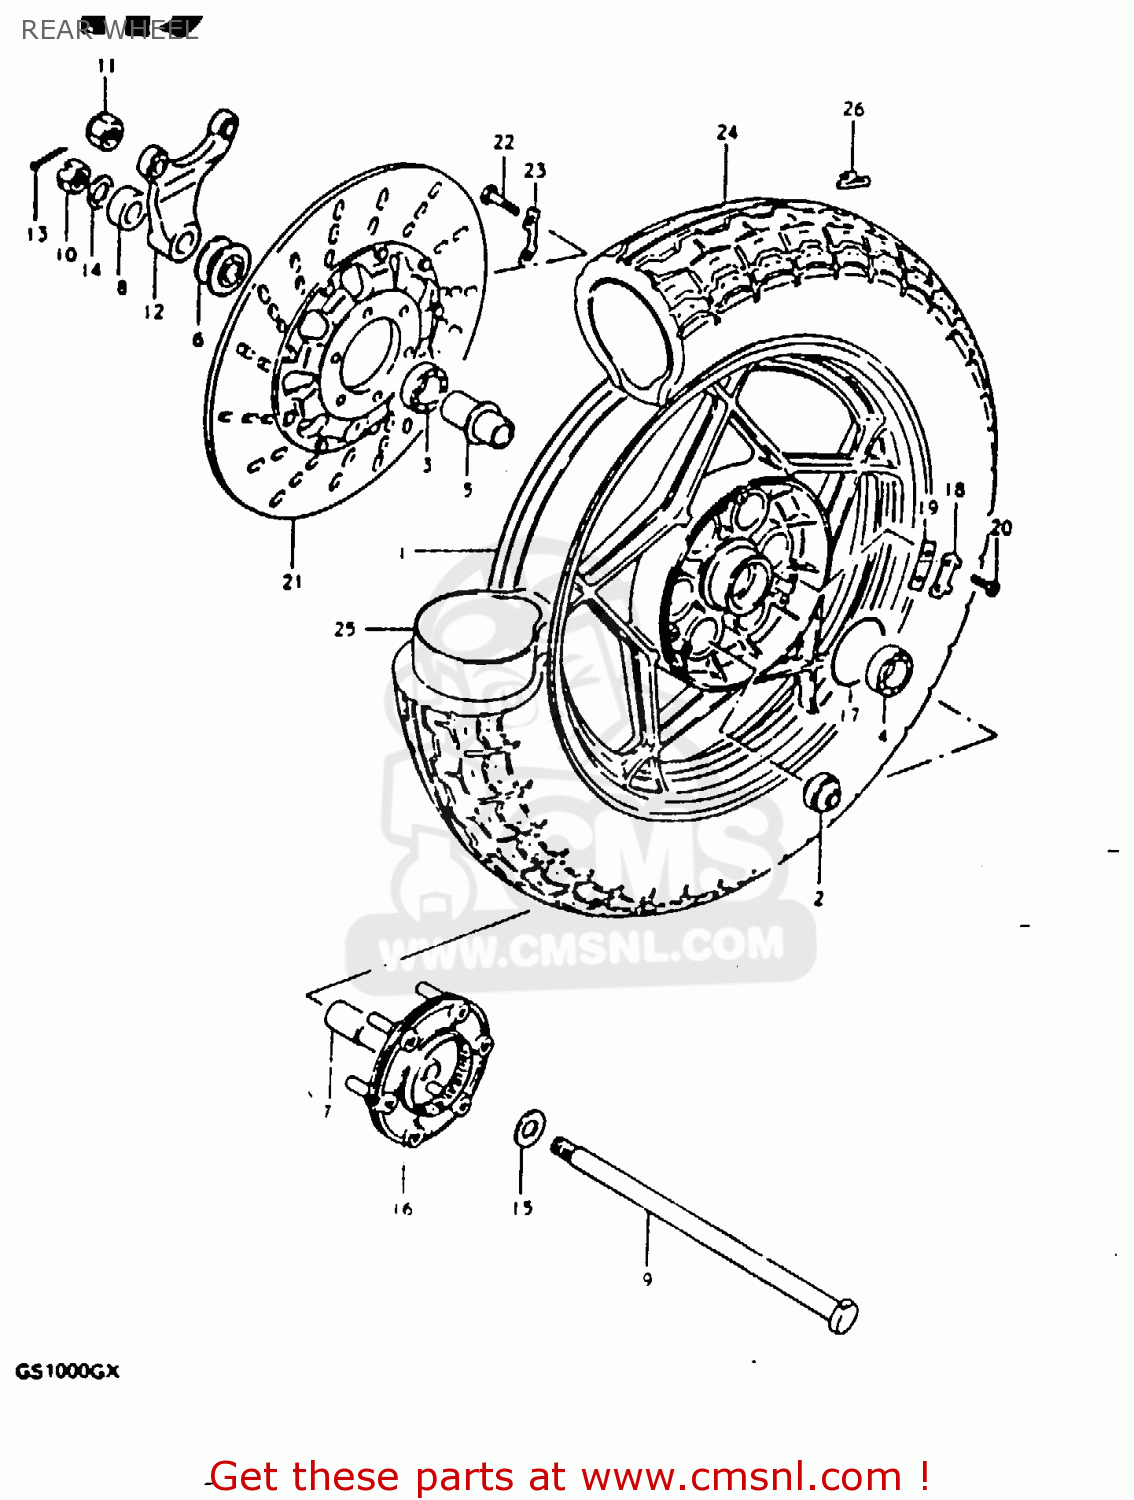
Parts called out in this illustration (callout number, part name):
1	CASTING WHEEL,REAR
2	BUSH
3	BEARING
4	BEARING
5	SPACER,REAR HUB BEARING
6	SPACER,REAR AXLE
7	SPACER,REAR AXLE,LEFT
8	SPACER (17X33X15.2)
9	AXLE,REAR
10	NUT
12	BRACKET,RR,CALIPER
13	PIN,COTTER
14	WASHER
15	WASHER (17.5X36X3.2)
16	JOINT ASSEMBLY,REAR HUB DRUM
17	O RING(D:2.1,ID:65)
18	JOINT WASHER
19	WASHER,THRUST(T:1.6)
20	SCREW
21	DISC,RR BRAKE
22	BOLT(8X30)
23	WASHER
24	TIRE
25	TUBE ASSEMBLY,WHEEL,INNER
26	BALANCER,WHEEL
